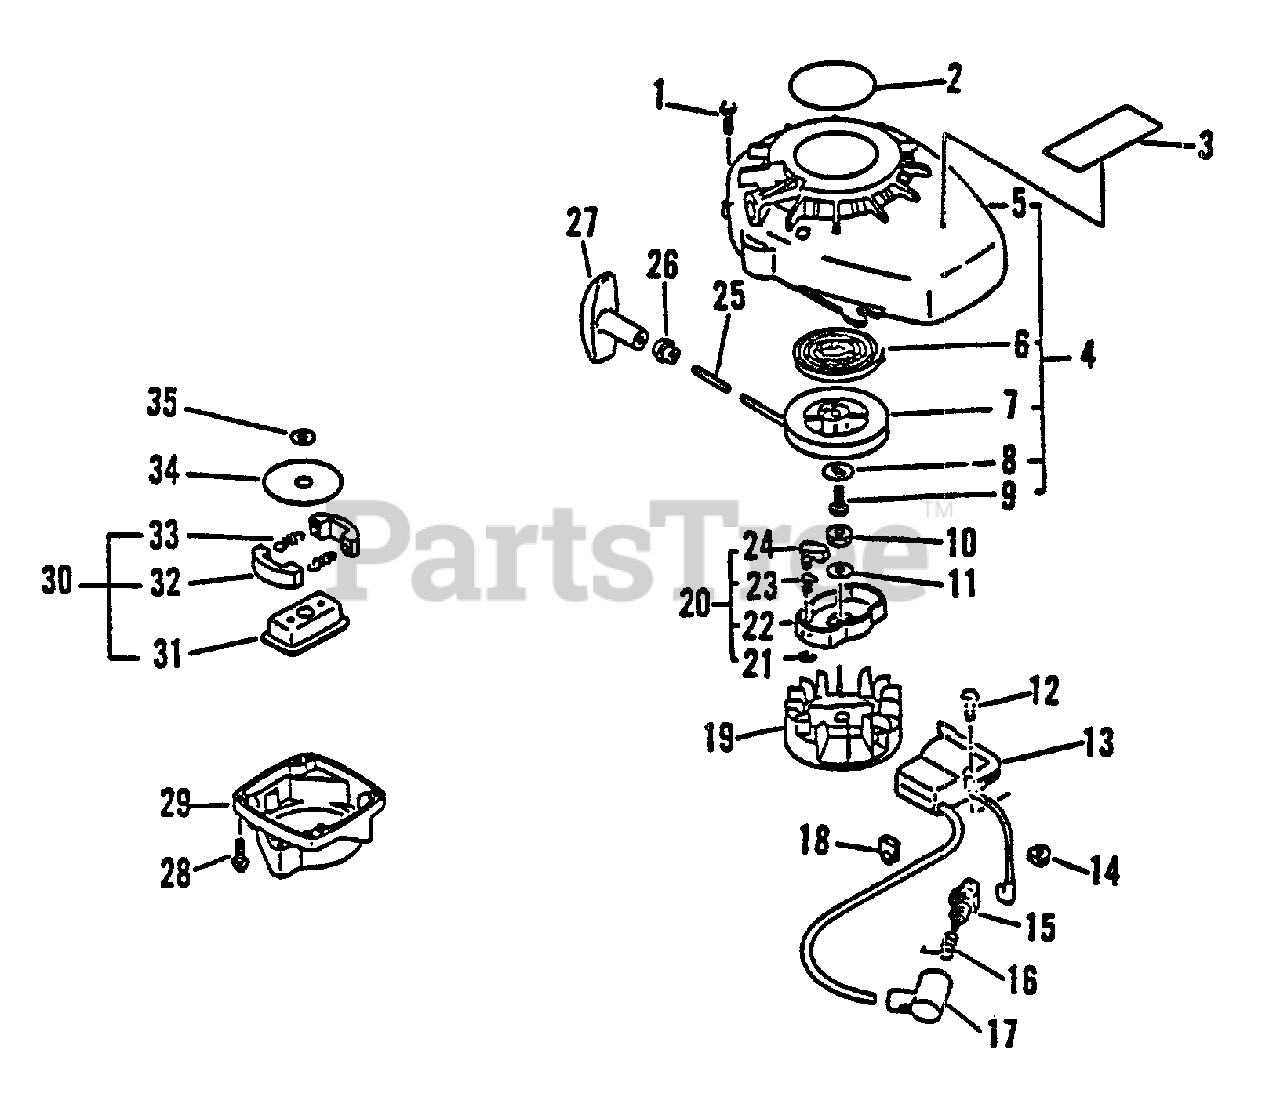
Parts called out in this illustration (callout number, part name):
1	SCREW - 4X16
2	LABEL - LESCO
3	LABEL - MODEL LHD-1700
4	STARTER ASSY
5	CASE, STARTER
6	SPRING, REWIND
7	REEL, ROPE
8	WASHER
11	WASHER - 8
12	SCREW - 4X22
13	COIL, IGNITION
15	SPARK PLUG -- BPM-6A
16	TERMINAL, SPARK PLUG CAP
17	CAP, SPARK PLUG
19	FLYWHEEL
20	STARTER PAWL ASSY
21	RING, RETAINING - 4
22	CATCHER, PAWL
23	SPRING, RETURN
24	PAWL, STARTER
25	ROPE, STARTER - 3X890
26	GUIDE, ROPE
27	GRIP, STARTER
28	SCREW - 4X16
29	CASE, CLUTCH
30	CLUTCH ASSY
31	HUB, CLUTCH
32	SHOE, CLUTCH
33	SPRING, CLUTCH
34	PLATE, CLUTCH
35	WASHER, CLUTCH
